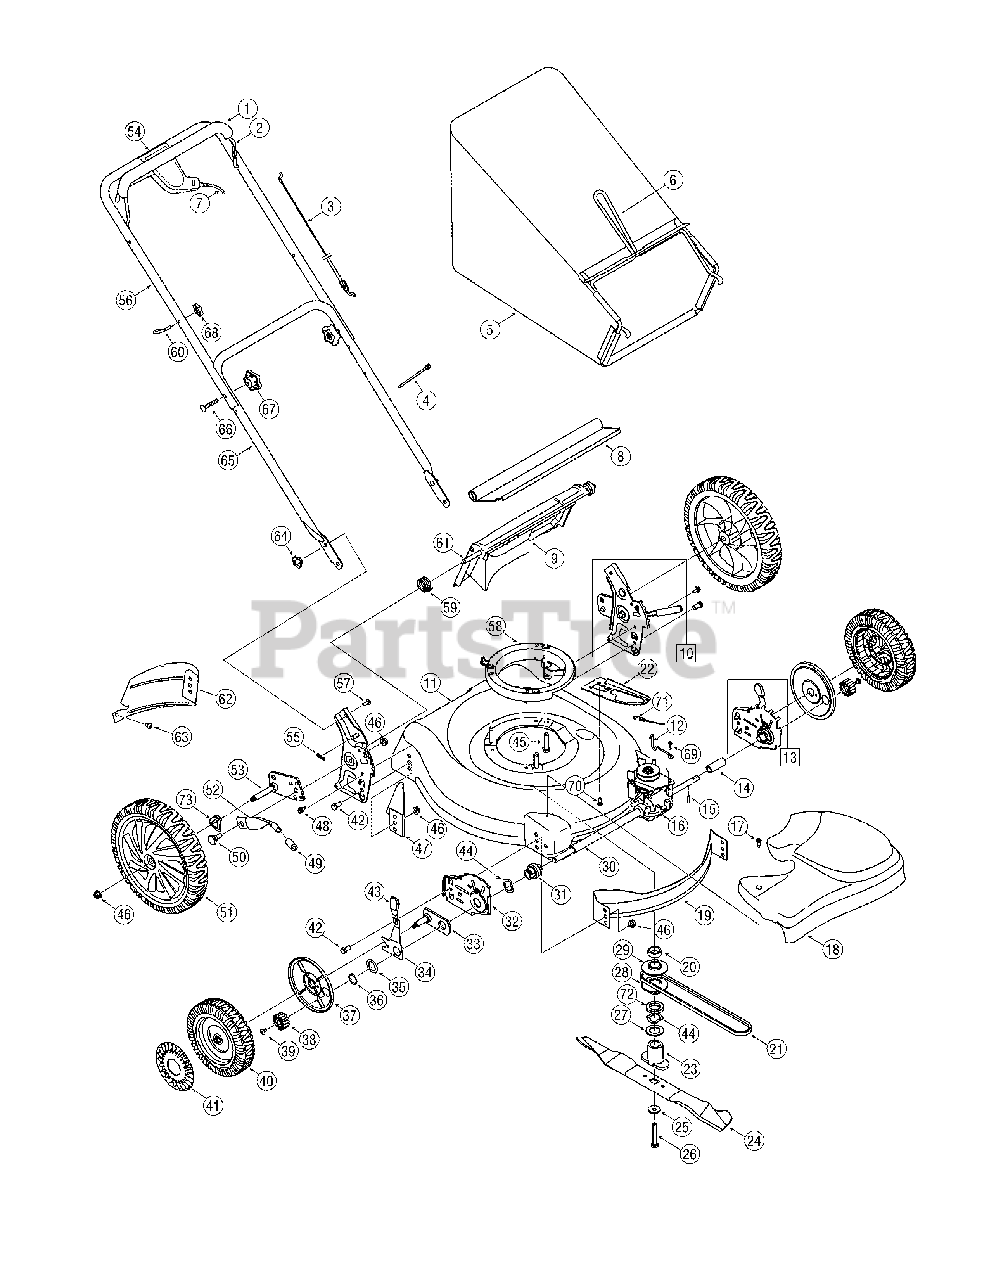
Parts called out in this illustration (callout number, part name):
1	Bail Cover
2	Blade Control
3	Control Cable 37.25-inch
4	Cable Tie
5	Grass Bag Assembly
7	Variable Speed Cable
8	Trailshield
9	Rear Door
10	Height Adj. Bracket Assy - LH
10	Height Adj. Bracket Assy - RH
11	21-inch Deck
12	Extension Spring
13	Front Height Adj. Assy - LH
13	Front Height Adj. Assy - RH
14	Sleeve Spacer .52 ID x 1.8 Lg
15	Dowel Pin
16	Transmission
17	Shoulder Screw
18	Deck Cover
19	Front Baffle
21	V-Type Belt
22	Cable Mount Bracket
23	Blade Adapter
24	21-inch Mulching Blade
25	Bell Washer, .396 x 1.140 x .095
26	Screw 3/8-24 x 2.5
27	Flat Washer, 1.031 x 1.620 x .095
28	Key Half Pulley
29	Upper Half Pulley
30	Sleeve Spacer, .52 Lg x 9.10
31	Front Bearing Assembly
32	Adjustment Plate RH
32	Adjustment Plate LH
33	Pivot Plate Assembly
34	Spring Lever RH
34	Spring Lever LH
35	Flat Washer 1.01 x 1.5 x .035
36	Snap Ring
37	Wheel Cover
38	Spur Gear 14T RH
38	Spur Gear 14T LH
39	Screw 1/4-20 x .39
40	Front Wheel 8 x 2.125 Zag
41	Hubcap
42	Screw 3/8-16 x .75
43	Knob
44	Wave Washer 1.5 x 1 x .029
45	Screw TT 3/8-16 x 1.875
46	Flange Lock Nut 3/8-16
47	Rear RH Baffle
48	Screw TT 1/4-20 x .625
49	Foam Grip
50	Shoulder Screw
51	Rear Wheel 12 x 2.125 Idle Zag
52	Spring Lever
53	Pivot Arm Assembly RH
53	Pivot Arm Assembly LH
54	Speed Control Assembly
55	Hairpin Clip
58	Engine Spacer
59	Torsion Spring RH
60	Eye Bolt
61	Pivot Rod
62	Rear Baffle LH
63	Screw AB 1/4-14 x .625
64	Wing Nut
65	Lower Handle
66	Carriage Bolt 5/16-18 x 2
67	Star Knob
68	Handle Knob
69	Torx Screw
70	Screw, 1/4-14 x .625
71	Belt Keeper Wire
72	Spacer, 1.004 x 1.375 x .25
73	Spring Washer, .500 x 1.00 x .022
